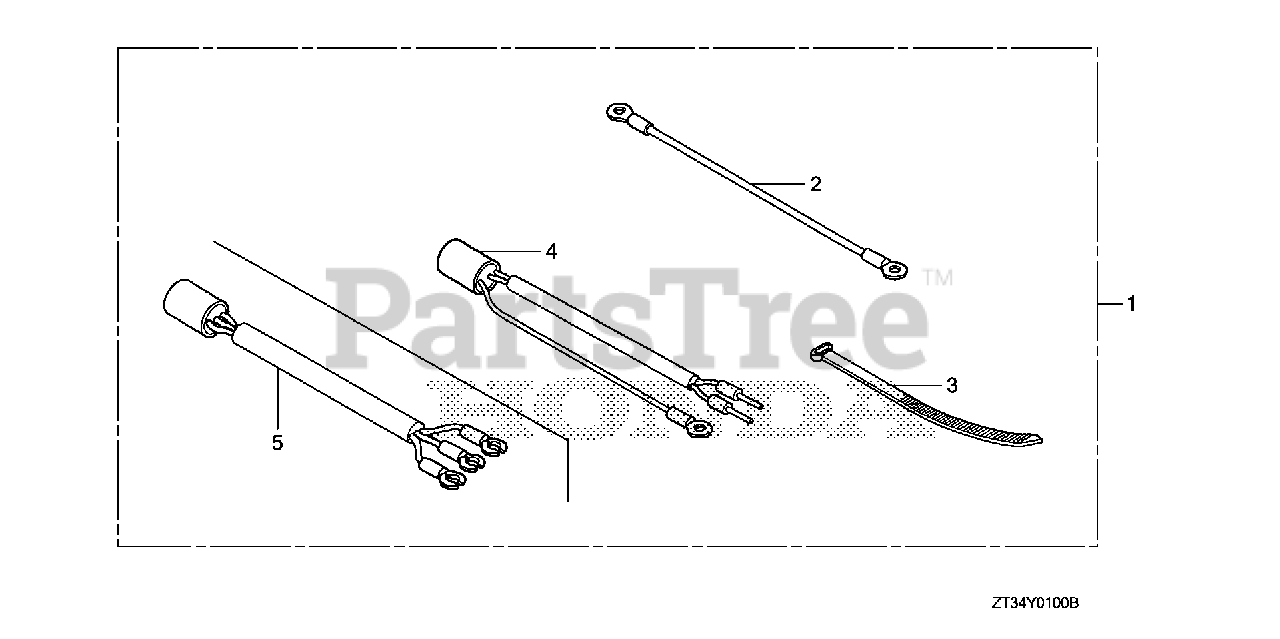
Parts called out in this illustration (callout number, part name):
1	FILTER KIT
2	WIRE, GROUND
3	BAND (BLACK 3.5X140)
4	FILTER ASSY., NOISE
